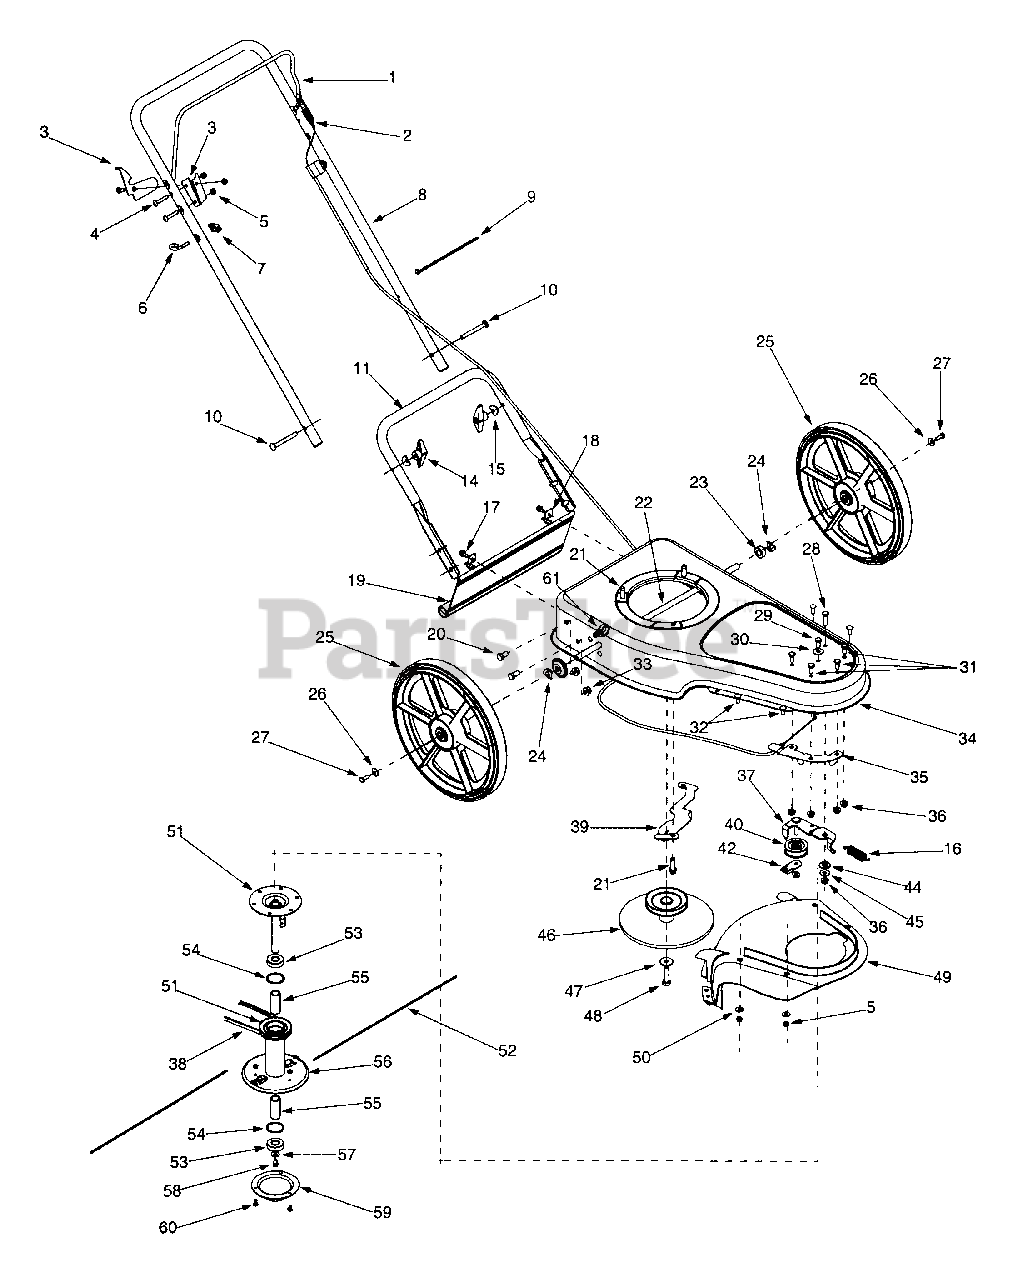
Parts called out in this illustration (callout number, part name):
3	Control Lock Bracket
4	Machine Screw 1/4-20 x 1.50
5	Hex Lock Nut 1/4-20
6	Eye Bolt 1/4-20
7	Wing Nut
10	Carriage Screw 5/16-18 x 2.0
13	Lower Handle Connector
14	Wing Nut
15	Shoulder Washer.320 ID x .93 OD
16	Extension Spring .50 Dia x 1.88 Lg
17	Hex Washer Screw 1 /4-14 x .625
18	Trail Shield Clip
19	Trail Shield
20	Hex Cap Screw 3/8-16 x .750
21	Hex Washer Screw 3/8-16 x 1.25
22	Trimmer Axle
23	Spacer.51 ID x 1.0 OD
24	Spacer Washer.501 ID x 1.0 OD
25	Wheel Assembly
26	Bell Washer.265 ID x .75 OD
27	Hex Cap Screw 1/4-20 x .75
28	Screw 5/16-18 x 1.25
29	Hex Cap Screw 5/16-24 x .625
30	Bell Washer.325 ID x .930 OD
31	Screw 5/16-18 x .75
32	Hex Carriage Screw 1/4-20 x .75
33	Flange Lock Nut 3/8-16
36	Flange Lock Nut 5/16-18
37	Idler Bracket Assembly
38	V-Belt
41	Torsion Spring
43	Idler Spacer
44	Idler Spacer
45	Flat Washer
46	Flywheel Pulley
47	Bell Washer 396 ID x 1.14 OD
48	Hex Cap Screw 3/8-24 x 1.50
49	Trimmer Deflector Assembly
50	Flat Washer.28 ID x .74 OD
51	Spindle Assembly
52	Trimmer Line 130 Dia
53	Ball Bearing
54	Retainer Ring
55	Spacer
56	Spindle Assembly Complete
57	Bell Washer 325 ID x .930 OD
58	Hex Cap Screw 5/16-24 x .625
59	Skid
60	Hex Cap Screw 1/4-20 x .50
61	Cable Retainer Clip
